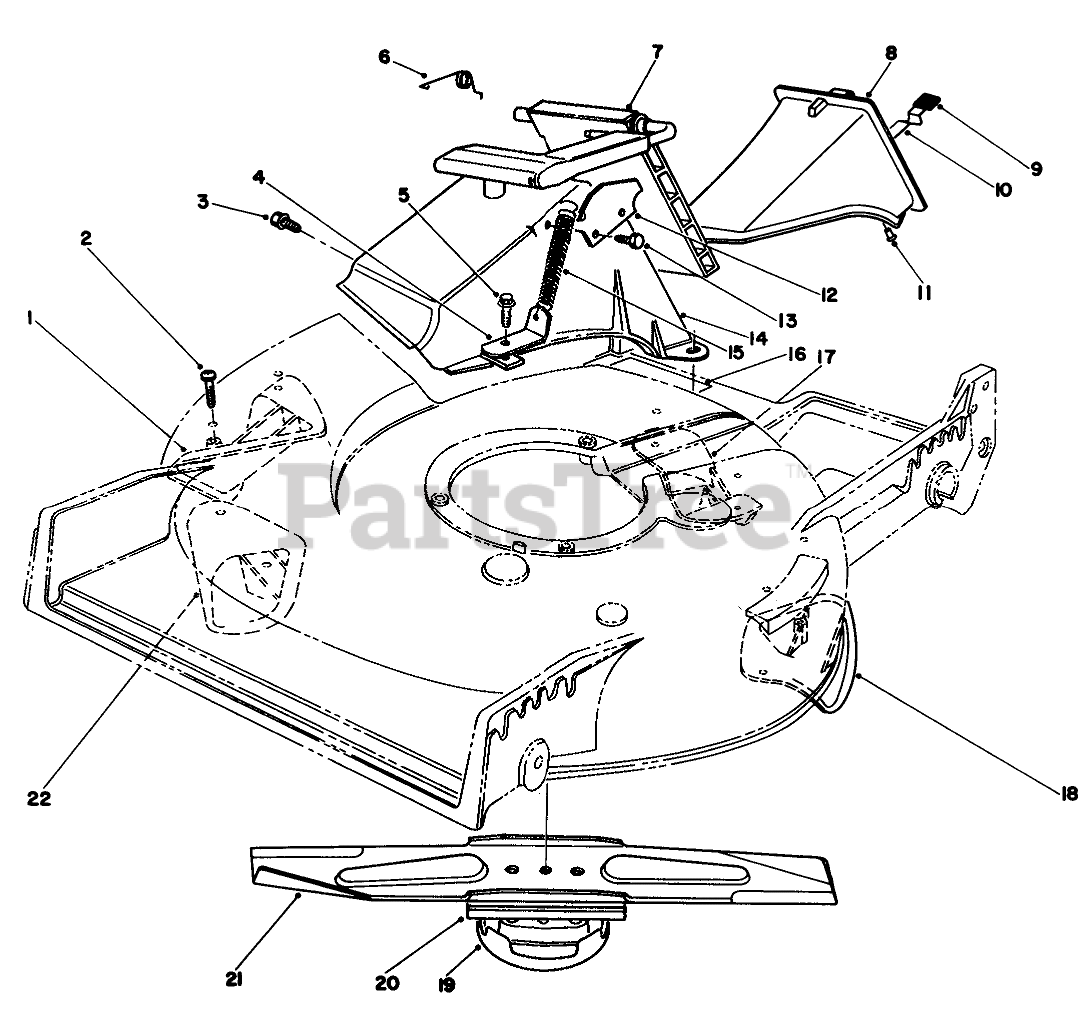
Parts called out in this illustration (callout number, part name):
1	KICKER
2	SCREW-PPH
3	SCREW AND WASHER ASM
4	Bracket-Spring
5	SCREW-HWH
6	RETAINER-DOOR
7	DOOR ASSEMBLY
8	Plug Assembly (Incl. Ref. #9-11)
9	GRIP-LATCH
10	LATCH-PLUG, DISCHARGE
11	RIVET-HEAD, FLAT
12	DOOR LATCH PLATE
13	SCREW-PLASTITE
14	DISCHARGE TUNNEL
15	SPRING-DOOR
16	DECAL
17	KICKER
18	KICKER
19	CUP-SCALP, ANTI
20	Stiffener
21	Blade Assembly (Incl. Ref. #20)
22	KICKER
